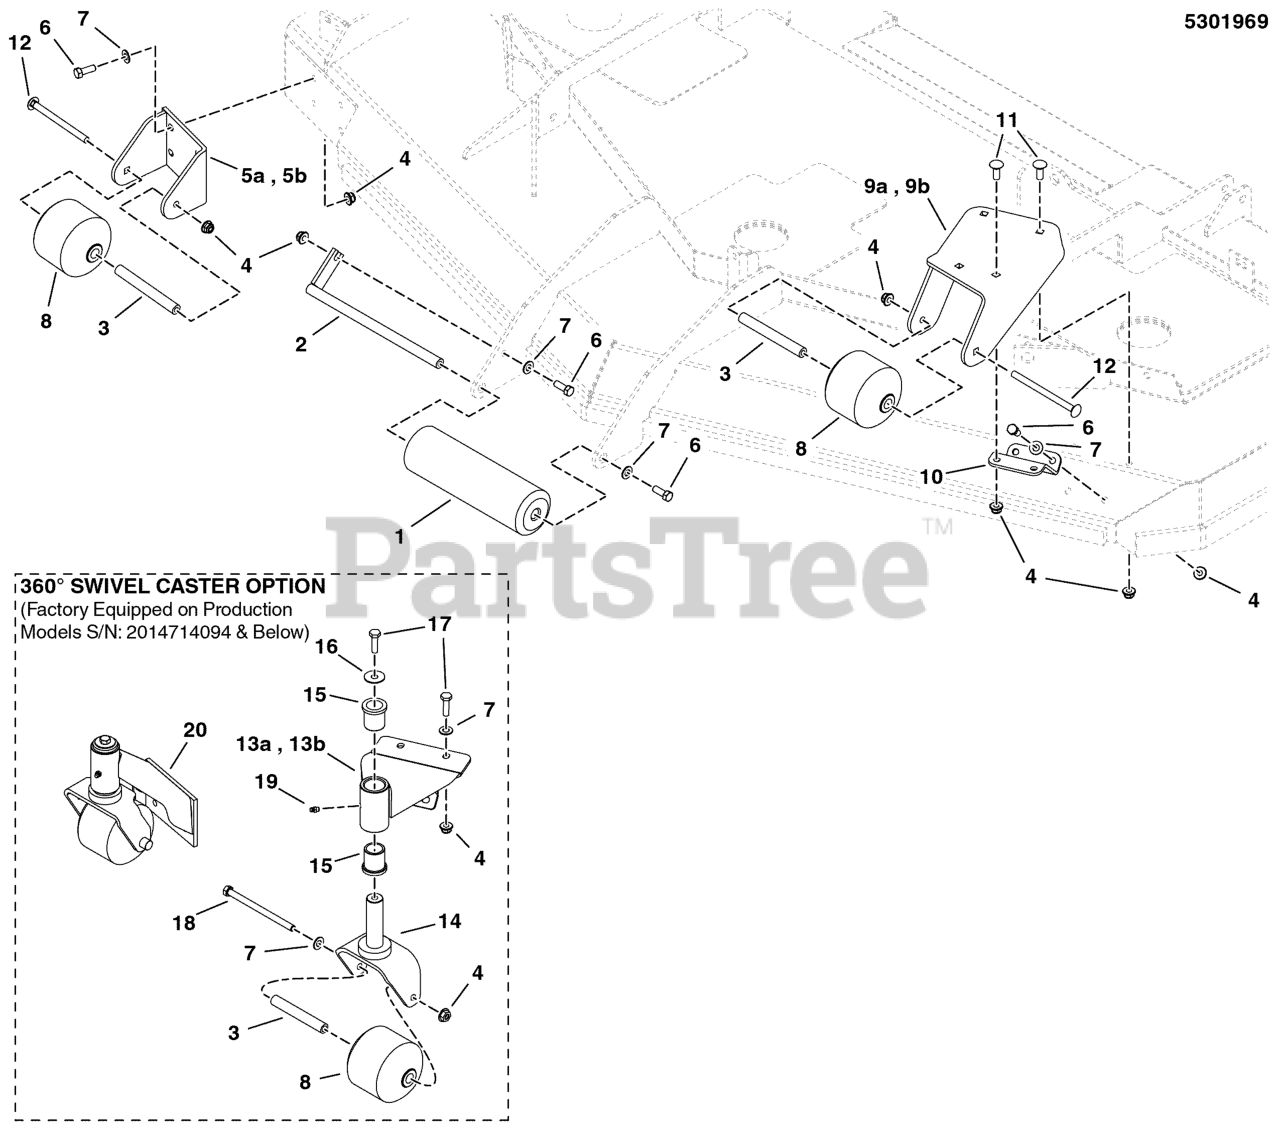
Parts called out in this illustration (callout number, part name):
1	ROLLER, DECK
3	SPACER, .38 X .63 X 4.31
4	NUT, 3/8-16 HEX NYLOCK FLANGE
6	BOLT, 3/8-16 X 1" GD5 CZ
7	WASHER, 3/8 SAE
8	ROLLER, SMALL
10	PLATE, ANTI-SCALP SUPPORT - RED
11	BOLT, RD HD SH SQ NK 3/8- 16X1.000 G5 BL
12	BOLT, 3/8-16 X 5-1/2, CARRIAGE
14	WELD, CASTER YOKE - RED
15	BUSHING, FLANGE
16	WASHER, .390 X 1.50 X .109, YZ
17	BOLT, 3/8-16 X 3/4" GD5 CZ
18	BOLT, 3/8-16 X 5-1/2" GD5 CZ
19	GREASE FITTING, 1/4-28 STRAIGHT
20	WELD, ANTI-SCALP, CASTER BRACKET - RED
